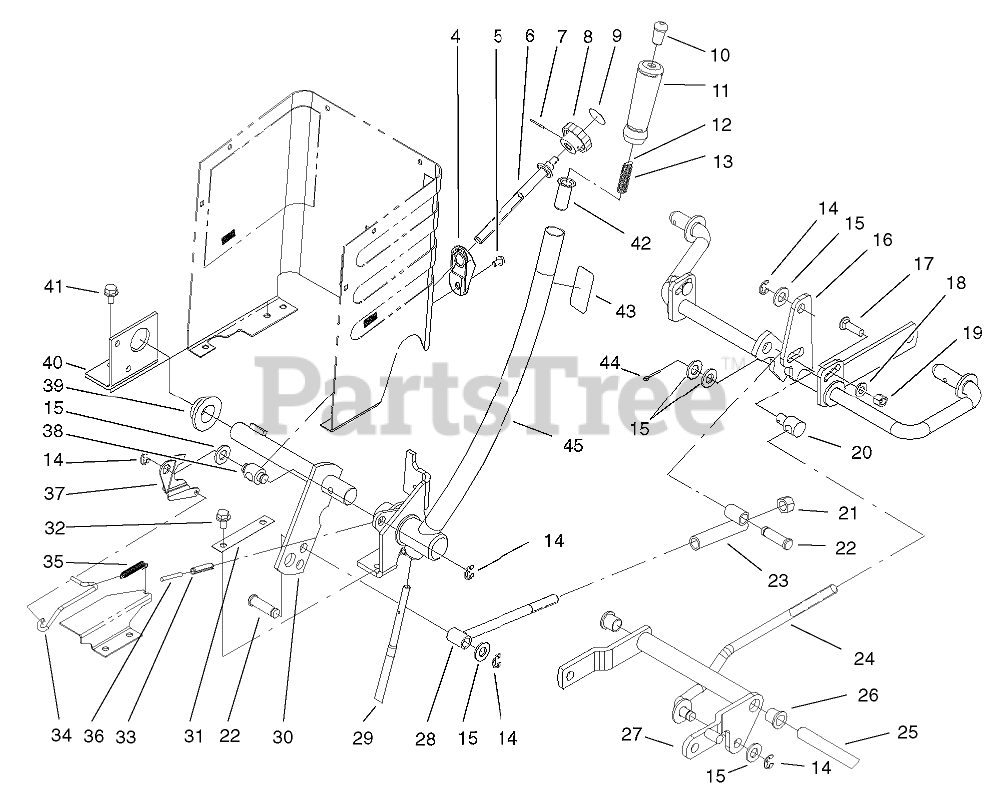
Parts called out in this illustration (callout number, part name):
4	WEDGE - HOC
5	SCREW-HWH
6	ROD - HOC
7	PIN-SPIROL
9	DECAL-HEIGHT KNOB
10	TIP-ROD
11	GRIP-HANDLE
12	PIN-SPIROL
13	SPRING-COMPRESSION
14	RING-RETAINING, EXTERNAL
15	WASHER-FLAT
16	SHAFT-GAGE
17	BOLT-CARR
18	WASHER-FLAT
19	NUT-LOCK, NI
20	ROD-TRUNNION LIFT
21	NUT-LOCK, NI
25	SHAFT-PIVOT, PEDAL
26	BUSHING-FLANGE
27	ARM-PIVOT
29	ROD-LEVER, LIFT
30	SHAFT-LIFT
32	SCREW-HWHTF
33	PIN-ROLL
34	ROD - HOC INDICATOR
35	SPRING - EXTENSION
36	PIN-SPRING
37	PLATE - HOC GAGE
38	TRUNNION
39	BEARING-FLANGE
40	BRACKET-PIVOT, LINKAGE
41	SCREW-HWHTF
42	RETAINER-SPRING
43	DECAL-LIFT
44	PIN-COTTER
45	LEVER-LIFT
